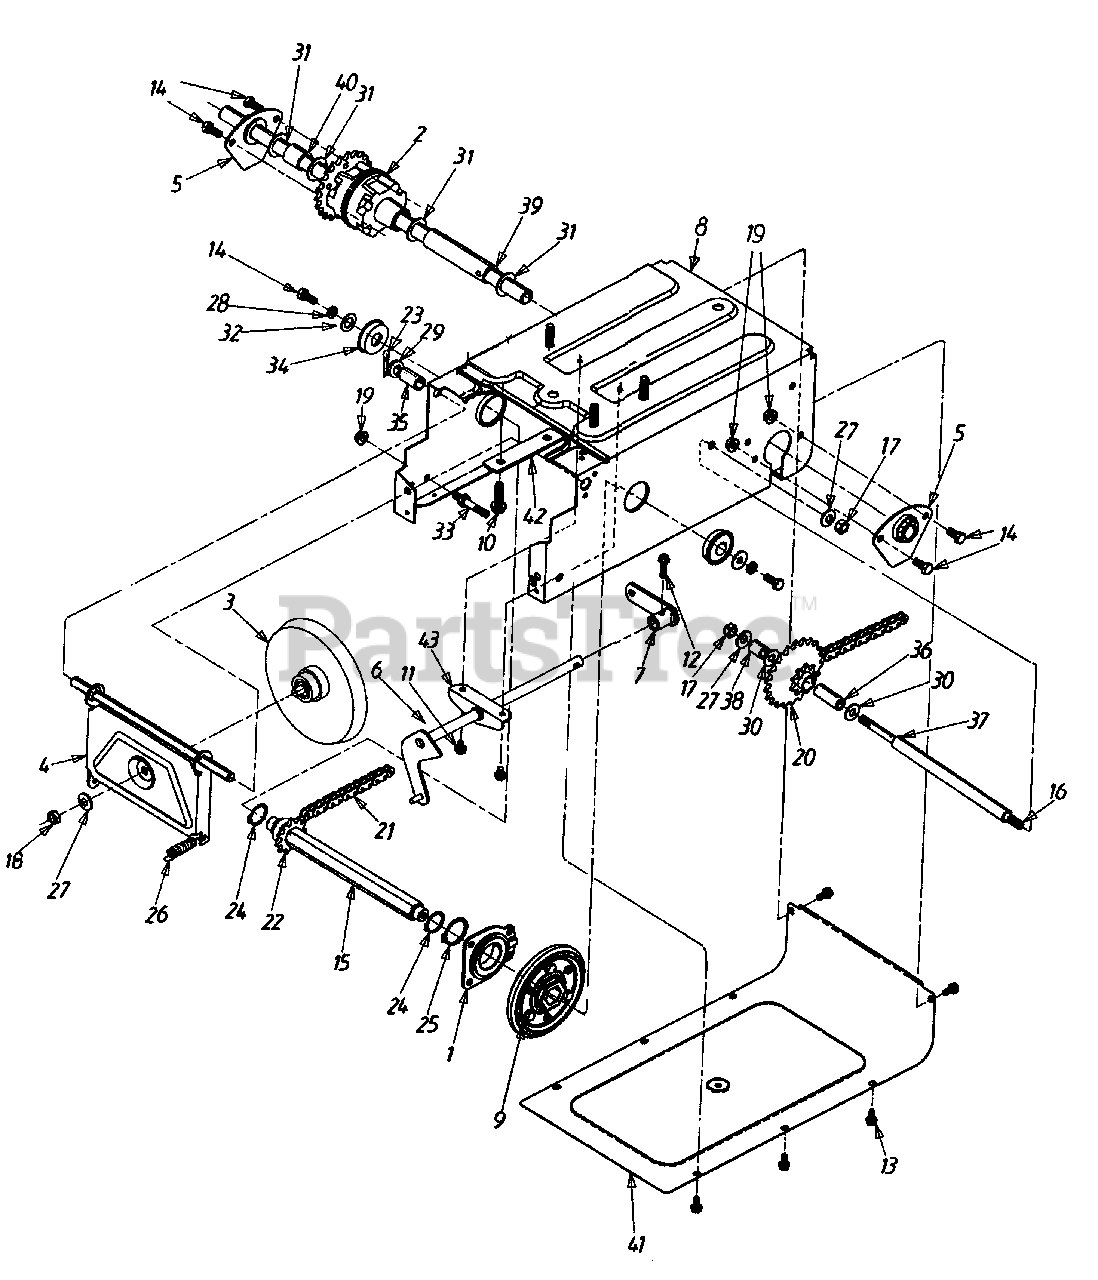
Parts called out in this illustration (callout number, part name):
1	BEARING ASSY-FRICTION WHEEL
2	DIFFERENTIAL ASSY COMP.
3	DISC-FRICTION WHEEL ASSY COMP.
6	SHAFT ASSY-SHIFT
9	WHEEL ASSY-FRICTION
10	SCREW-HEX SELF-TAP
11	SCREW-HEX WASHER
12	SCREW-HEX WASHER
13	SCREW-HEX
14	SCREW-HEX
15	SHAFT-HEX
16	SHAFT-JACK
17	NUT-HEX
18	NUT-HEX JAM
19	NUT-HEX FLANGE LOCK
20	SPROCKET & HUB
21	CHAIN
22	SPROCKET 11T
23	PIN-COTTER
24	RING-SNAP
25	RING-SNAP
26	SPRING-EXTENSION
27	WASHER-BELL
28	WASHER-LOCK
29	WASHER-FLAT
30	WASHER-FLAT
31	WASHER-FLAT
32	WASHER-FLAT
33	BOLT-IDLER
34	BEARING-BALL
35	SPACER
36	SLEEVE
37	SPACER
38	SPACER
39	SPACER
40	SPACER
